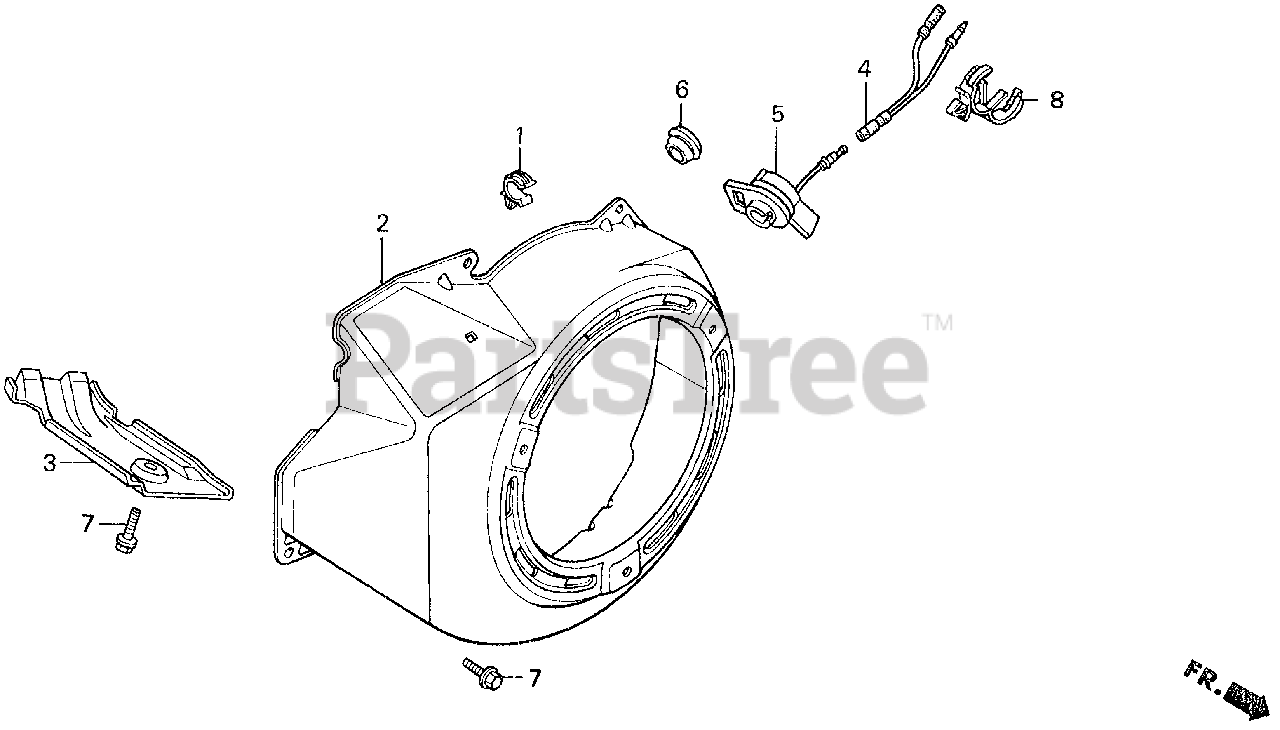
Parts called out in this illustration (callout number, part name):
1	CLIP, TUBE
2	COVER, FAN *R8* (BRIGHT RED)
2	COVER, FAN *NH246* (LOOSY GRAY)
3	SHROUD
4	SUB-HARNESS
5	SWITCH ASSY., ENGINE STOP
7	BOLT, FLANGE (6X12) (CT200)
8	CLIP, WIRE HARNESS
